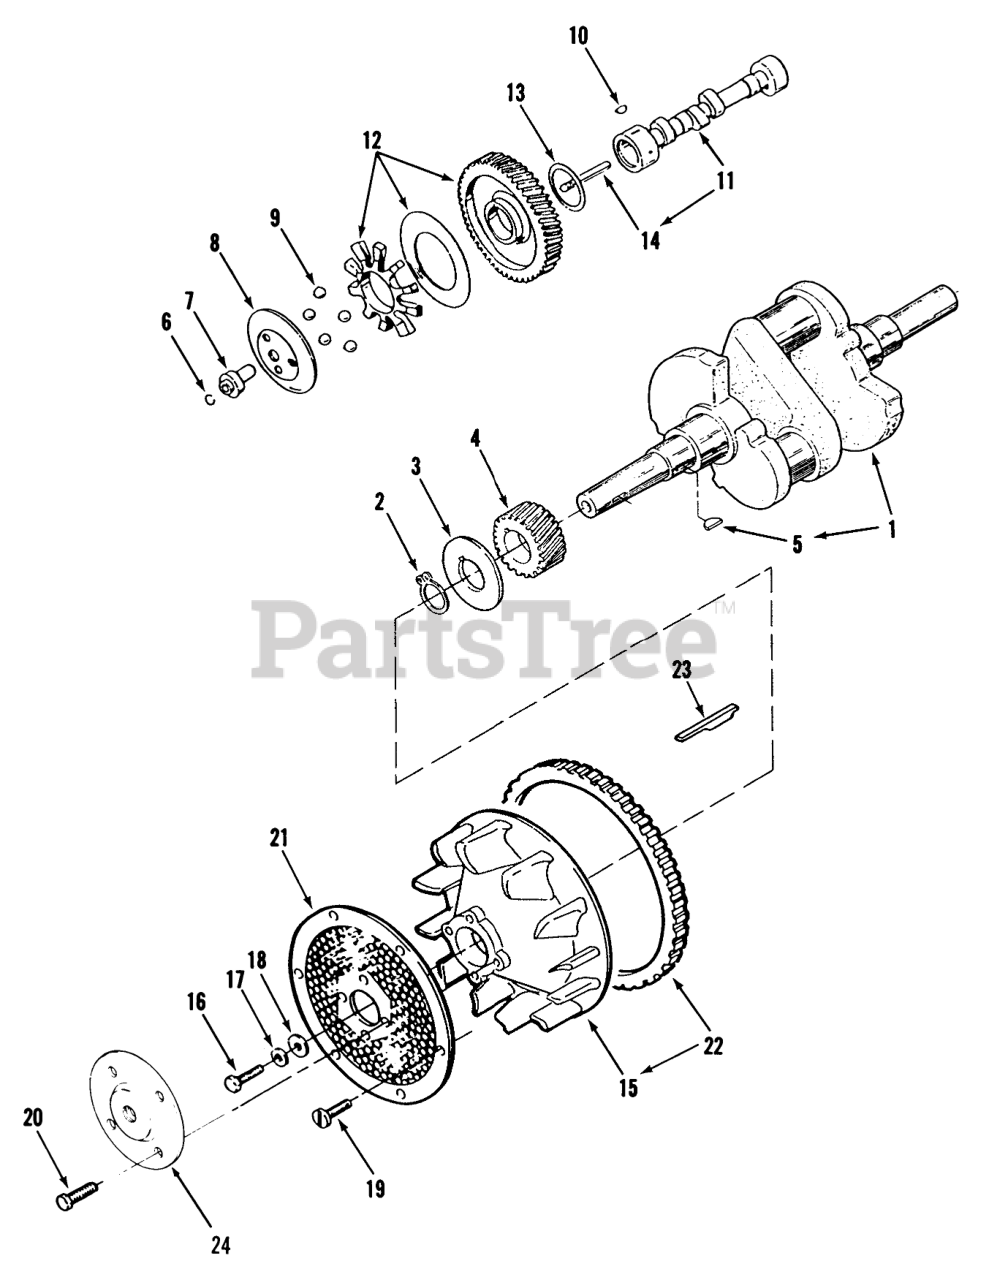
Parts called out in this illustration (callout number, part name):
1	CRANKSHAFT
2	Retaining Ring
3	Washer
4	Gear
5	Key
6	Retaining Ring
7	Governor Cup Hub
8	Cup-Governor
9	Ball
10	Key
11	CAMSHAFT (16&18HP)
12	Camshaft Gear with Spacer and Plate
13	Washer
14	Pin
15	Flywheel-w/Ring Gear
16	Screw
17	Washer
18	Washer
19	Bolt
20	Locking Bolt
21	Air Inlet Screen
22	Gear-Ring
23	Key
24	LIFTING-BRKT (ZINC)
